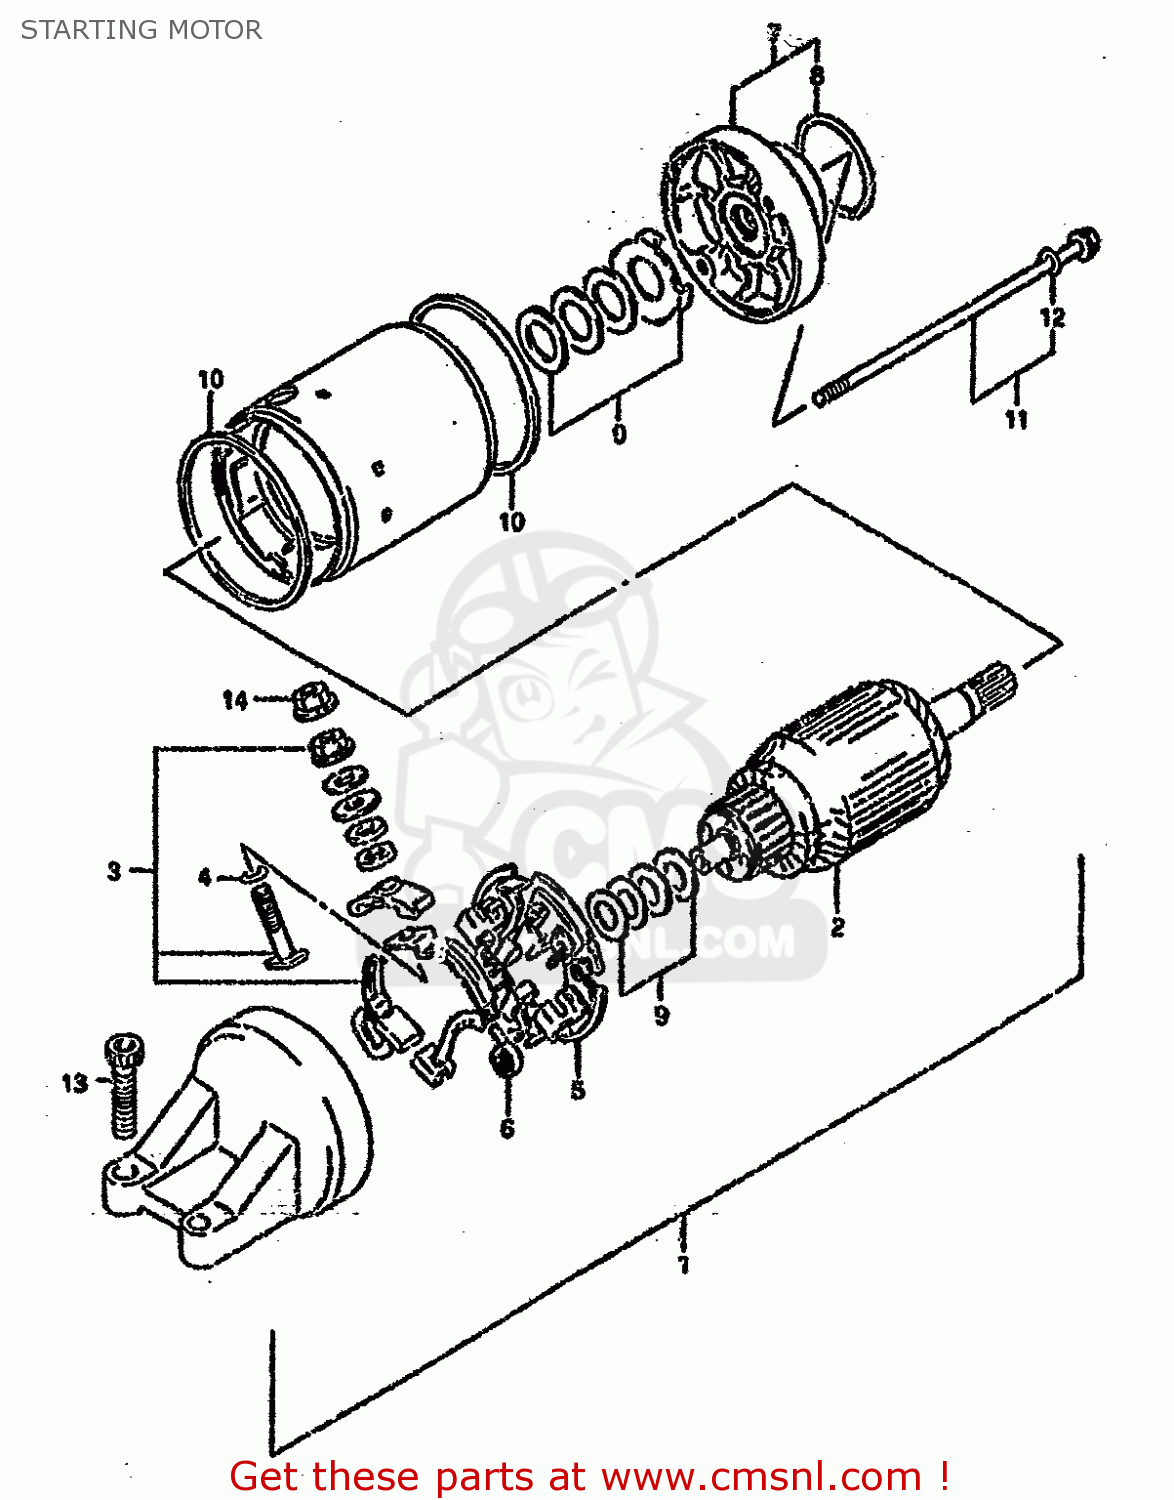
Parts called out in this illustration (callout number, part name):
1	MOTOR ASSEMBLY,STARTING
2	ARMATURE
3	TERMINAL SET,BRUSH,PLUS
4	O RING
5	BRUSH,HOLDER SET
6	SPRING,BRUSH
7	BRACKET ASSEMBLY,FRONT
8	O RING
9	SHIM SET,STARTING MOTOR
10	O RING
11	BOLT SET,STARTING MOTOR
12	O RING
13	BOLT,OIL PAN
14	NUT
